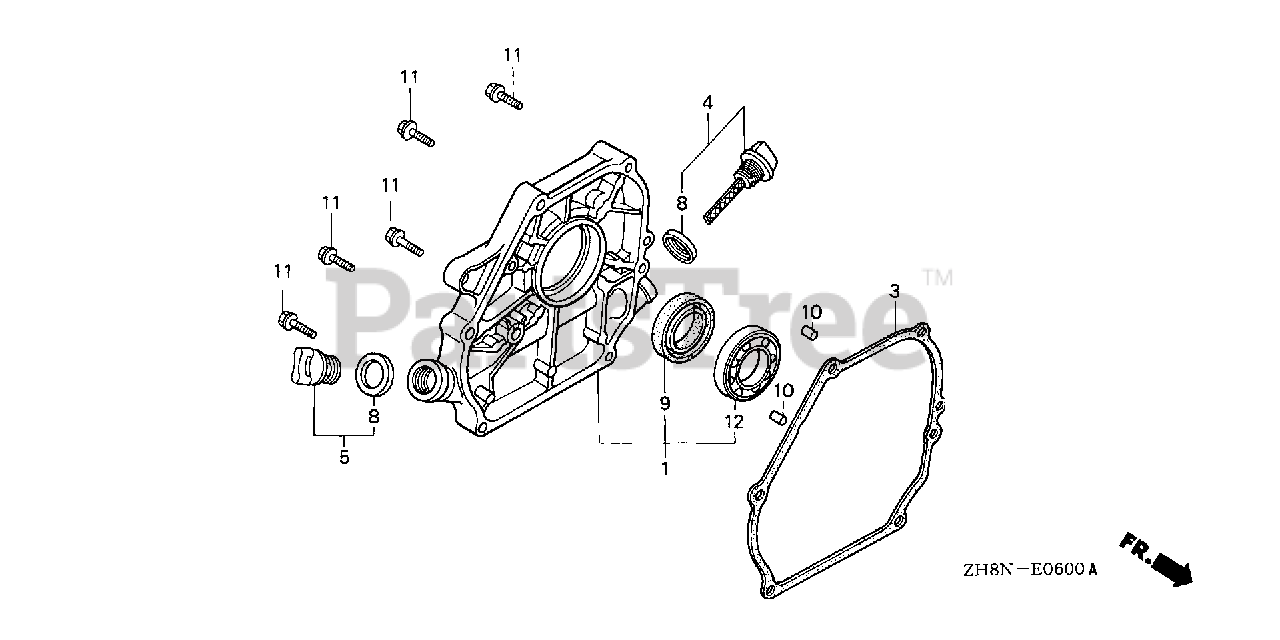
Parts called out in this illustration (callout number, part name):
1	COVER ASSY., CRANKCASE (S-TYPE)
3	GASKET, CASE COVER
4	CAP ASSY., OIL FILLER
5	CAP ASSY., OIL FILLER
8	GASKET, OIL FILLER CAP
9	OIL SEAL (25X41X6)
10	PIN A, DOWEL (8X14)
11	BOLT, FLANGE (8X32)
12	BEARING, RADIAL BALL (6205)
